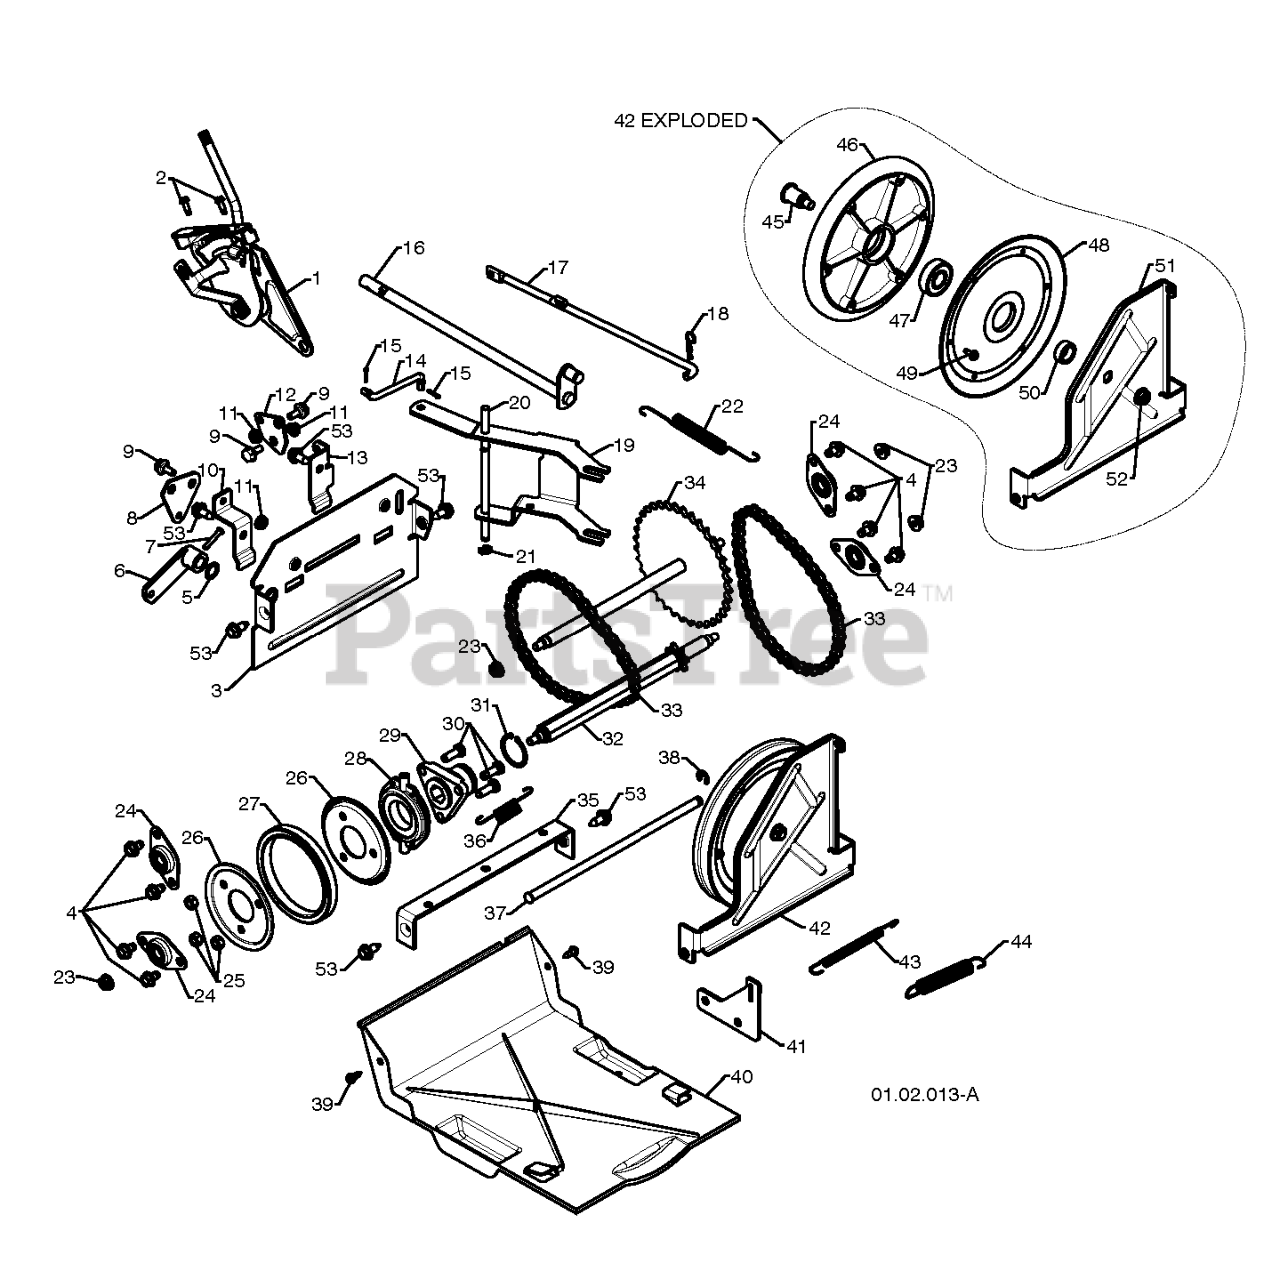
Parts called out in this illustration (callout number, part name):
1	HEAD ASSY SPEED
2	SCREW #10-24 X 5/8
3	PLATE.END.CHAIN.ASM.PNT.ORANGE
4	Screw 5/16-18 x 1/2 Hex, Self Tapping 5/16-18 x 1/2
5	THRUST WASHER
6	ARM, AUGER CONTROL
7	CLEVIS PIN
8	PLATE.SHIFTER.YZ
9	BOLT.SHOULDER.3/X.25
10	RP BRACKET.SHIFTER.PLATE
11	NUT.HEX.FLANGE.1/4
12	PLATE.CLUTCH.
13	BRACKET.CLUTCH.PLATE
14	LINK, SPEED CONTROL
15	RETAINER CLIP
16	CONTROL.SHAFT.ASM
17	ROD.CLUTCH.SWING.PLATE
18	SPRING RETAINER
19	YOKE.SHIFTER.SPEED
20	ROD.PIVOT.SHIFTER
21	KLIP RING TI
22	SPRING.TRACTION.RETURN
23	NUT.LOCK.5/16-18
24	BEARING FLANGE BALL
25	NUT.CENTERLOCK.5/16-
26	PLATE.RUBBER.WHEEL.BLACK
27	RING, RUBBER WHEEL
28	TRUNNION BEARING ASSY
29	HUB, RUBBER WHEEL
30	BOLT
31	RETAINING RING (2 2)(3 2)
32	SHAFT.HEX.W/SPOCKET
33	CHAIN.DRIVE.SNOWTHROWER.#420
34	SPROCKET WELDMENT
35	BRACKET.YOKE.SHIFTER.BLACK
36	SPRING, BIAS
37	ROD.PIVOT.SWING.PLATE.SNOW
38	E-RING.RETAINER.REINFORCED.375
39	SCREW, HEX HEAD, TAPPING
40	PAN.BOTTOM.PLASTIC
41	BRACKET.TRACTION.SPRIN
42	RP.PULLEY.PLATE.ASM.DRIVE
43	SPRING.TRACTION.IDLER
44	SPRING, BRAKE
45	SHAFT.FRICTION.PULLEY.SNOW
46	PULLEY.PLATE.ASM.DRIVE
48	RP PULLEY.HALF.TRACTION
50	SPACER BEARING
51	PLATE.SWING.DRIVE.PNT
52	FLANGED LOCKNUT 3/8-16 ZINC
53	BOLT.HEX.HD.WASHER.5/16-18X.75
